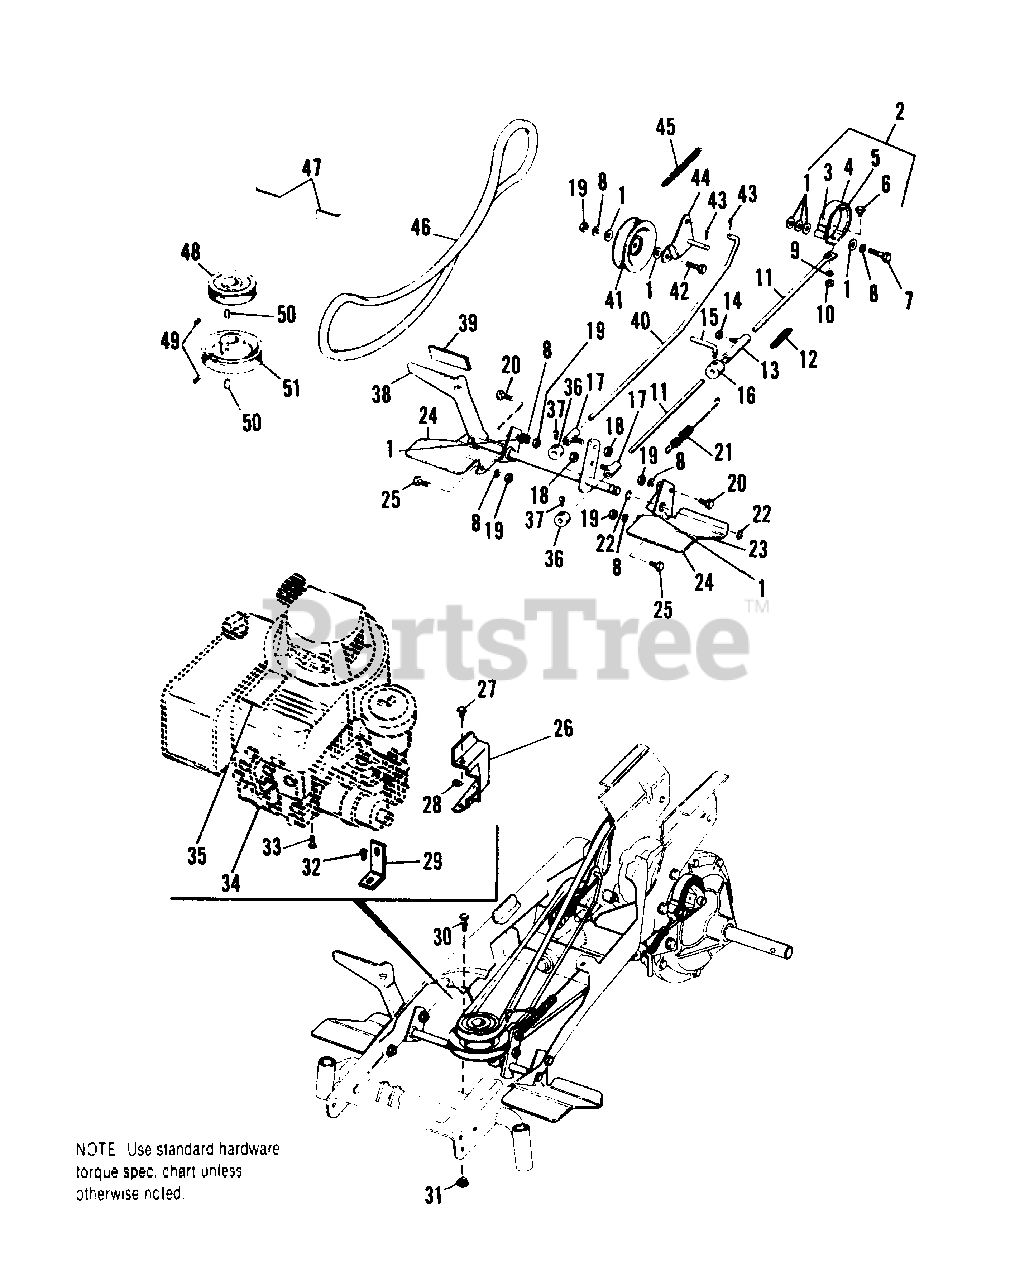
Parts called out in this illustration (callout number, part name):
1	WASHER, Plain, 5/16
2	BAND ASSY., Brake
3	RIVET, #7 x 1/4
4	BAND, Brake
5	LINING, Brake
6	CAPSCREW, Hex, 1/4-20 x 1/2
7	CAPSCREW, Hex Hd., 3/8-16 x 1-1/2
8	LOCKWASHER, 3/8
9	LOCKWASHER, 1/4
10	NUT, Hex, Full, 1/4-20
11	ROD, Brake
13	GUIDE ASSY., Rod
14	LOCKNUT, Hex, 1/4-20
15	LOCK, Parking Brake
16	COLLAR, Parking Brake
17	GUIDE ASSY., Rod
18	LOCKNUT, Hex, 5/16-18
19	NUT, Hex, Full, 3/8-16
20	CAPSCREW, Hex Hd., 3/8-16 x 1
22	RING, Retaining
23	FOOTREST, L.H.
24	COVER, Footrest
25	CAPSCREW, Hex Hd., 3/8-16 x 3/4
26	DEFLECTOR, Muffler
27	SCREW, Self Tapping, #14 x 5/8
28	NUT, Speed
30	CAPSCREW, Hex Hd., 5/16-18 x 1-1/2
31	LOCKNUT, Hex, Flange, 5/16-18
32	SCREW, Hex, Taptite, 1/4-20 x 3/8
33	SCREW, Hex, Washer Hd., 3/8-16 x 1-1/4
34	ENGINE, Briggs & Stratton
35	FILM, Engine Cover
36	COLLAR, Set
37	SETSCREW, 1/4-20 x 3/8
38	SHAFT ASSY., Clutch
39	PAD, Pedal
40	ROD, Clutch
41	PULLEY, Idler
42	CAPSCREW, Hex Hd., 3/8-16 x 1-1/4
43	PIN, Cotter, 1/8 x 3/4
44	BRACKET ASSY., Pulley
45	SPRING, Return (990418 Only)
45	SPRING, Return
46	V-BELT, Drive
47	STOP, Belt
48	PULLEY, Engine, Small
49	SETSCREW, 5/16-18 x 1/2
51	PULLEY, Engine, Large
